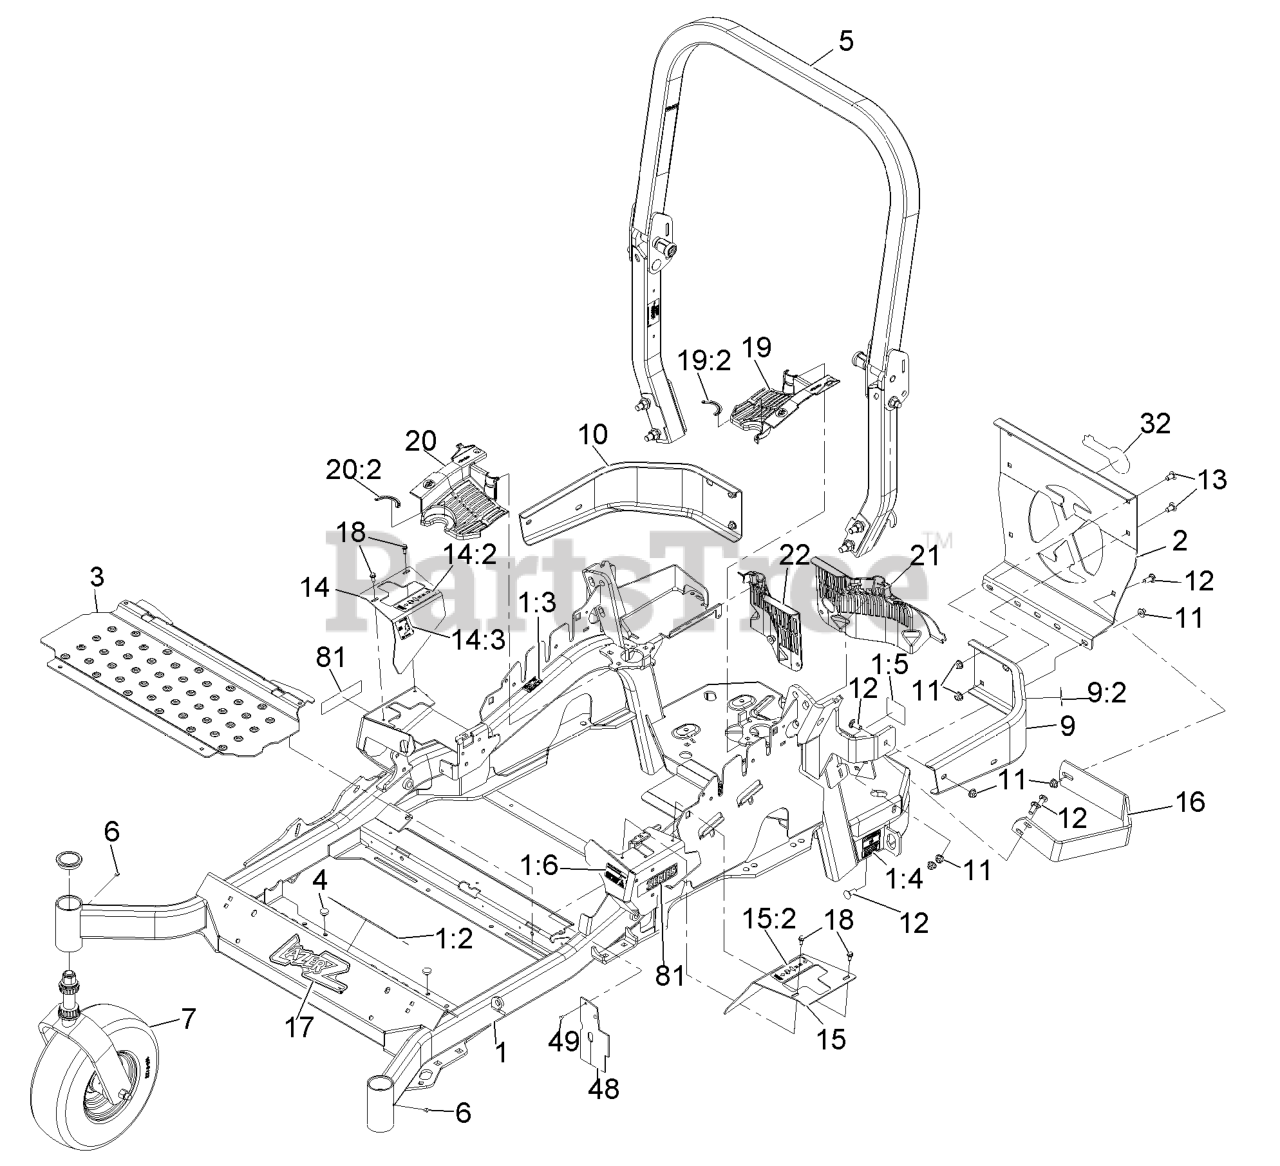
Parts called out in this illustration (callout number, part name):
1	MAIN FRAME ASM
1:2	DECAL-CAUTION
1:3	DECAL-SLOPE
1:4	DECAL-BELT DRIVE
1:5	DECAL-SPARK ARRESTER
1:6	DECAL-FUEL FILL
2	PLATE,REAR GUARD
5	ASM,ROPS SERVICE EXMARK
7	Caster Wheel Asm
9	LH BUMPER ASM
9:2	DECAL-CAUTION
10	BUMPER-RH
11	NUT-HF, NI
12	SCREW-CARR
13	SCREW-CARR
14:2	DECAL-MOTION CONTROL
15	LH MOTION CONTROL COVER ASM
15:2	DECAL-MOTION CONTROL
17	DECAL,LAZER MODEL
18	SCREW-HWH
19	LH HYDRO GUARD ASM
19:2	DECAL-HYDRO OIL
20	RH HYDRO GUARD ASM
20:2	DECAL-HYDRO OIL
21	GUARD-HYDRO REAR, LH TRIM
22	GUARD-HYDRO, REAR (RH)
48	DEFLECTOR-AIR FLOW
49	RIVET-POP
81	DECAL-X-SERIES
